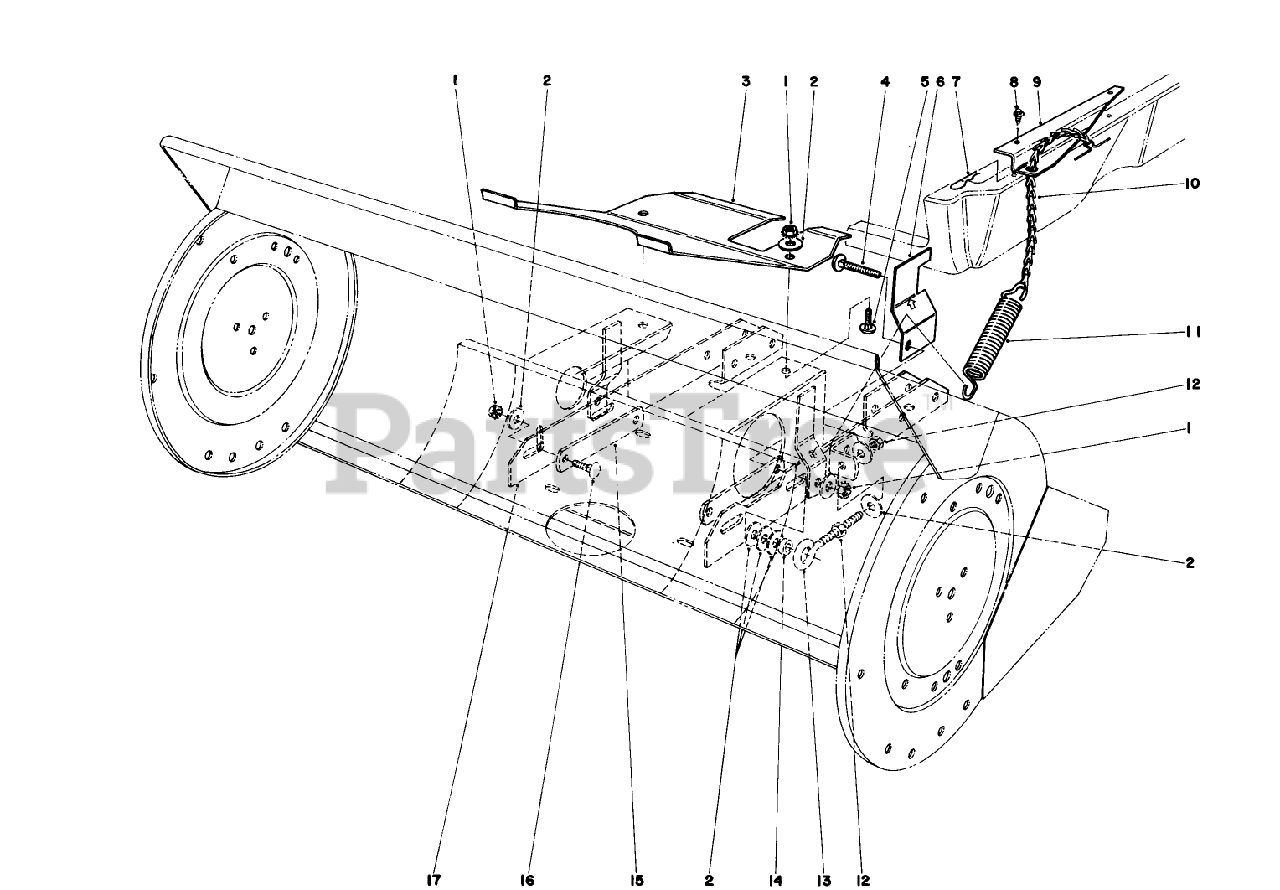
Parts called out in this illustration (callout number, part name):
1	NUT-KEPS
2	WASHER-FLAT
4	SCREW-CARR
5	SCREW-CARR
7	PIN-HAIR
8	SCREW-HWHTF
12	NUT-HEX
16	BOLT-CARR
